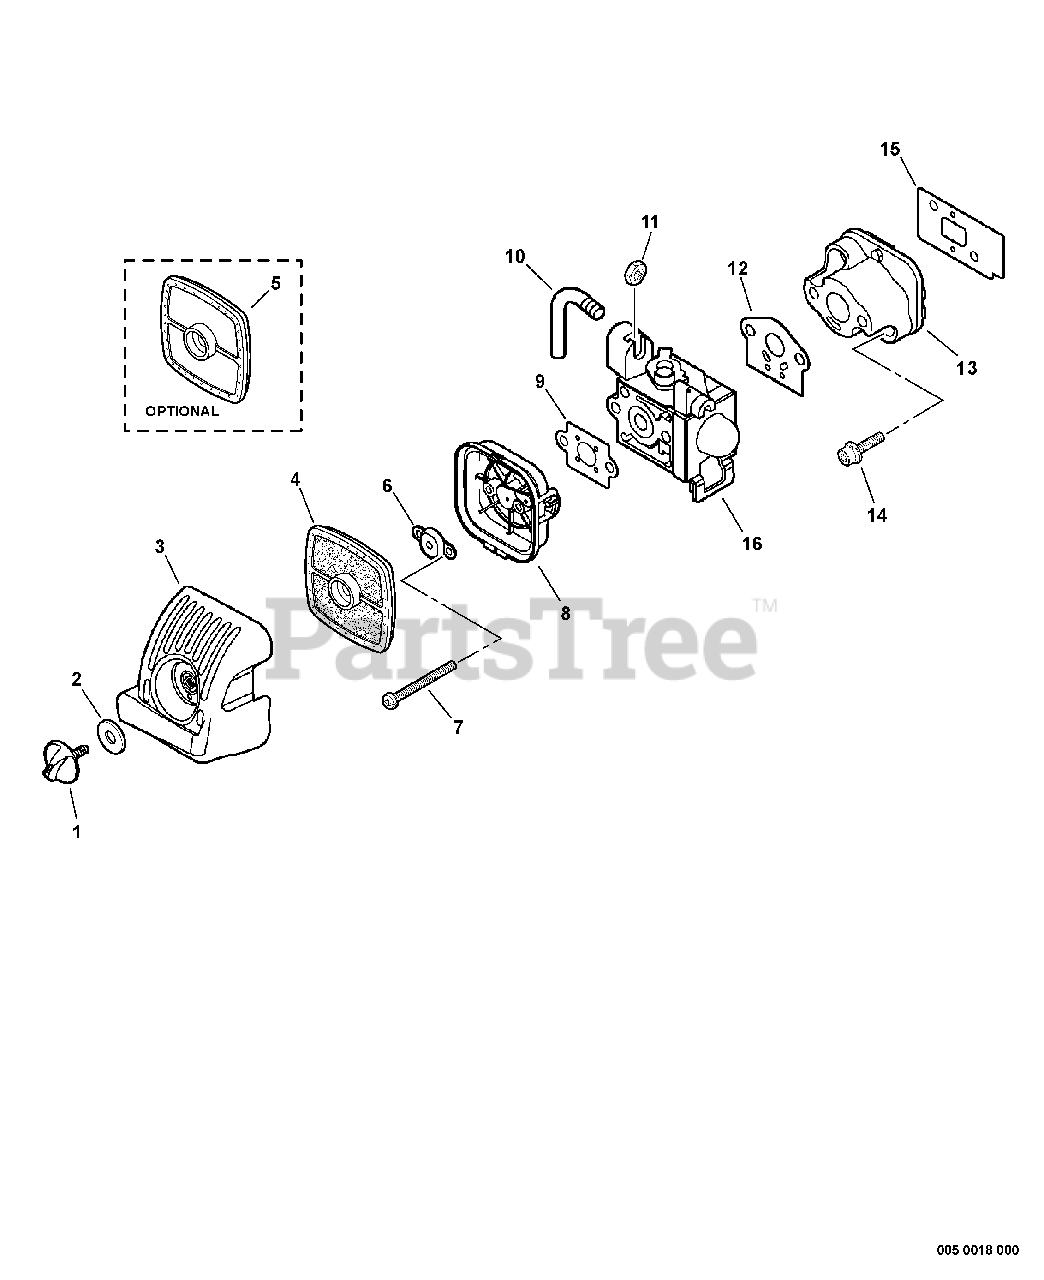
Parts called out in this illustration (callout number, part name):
1	THUMBSCREW
3	COVER, AIR FILTER
4	FILTER, AIR - DOUBLE LAYER
5	FILTER, AIR - SINGLE LAYER
6	PLATE, PREVENT
7	SCREW - 5X60
8	AIR FILTER CASE ASSY
9	GASKET, INTAKE
10	CONNECTOR, THROTTLE CABLE
12	GASKET, INTAKE
13	INSULATOR, INTAKE
14	SCREW - 5X25
15	GASKET, INTAKE
16	CARBURETOR
